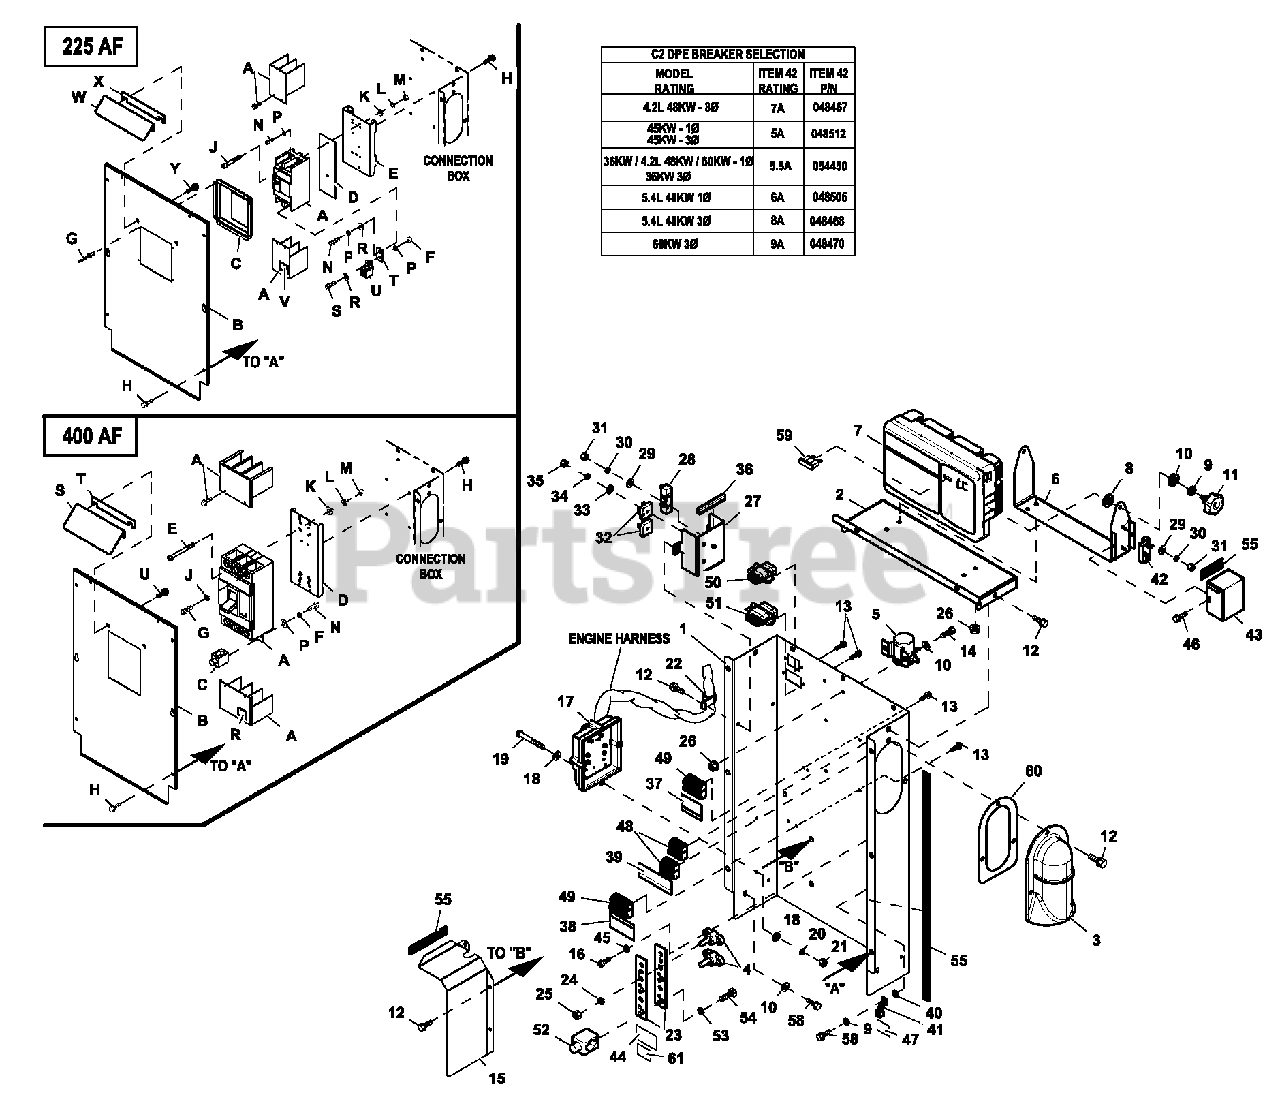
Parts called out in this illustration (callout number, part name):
1	BACK PANEL CONBOX SUPPORT C2
2	TOP PANEL CONBOX SUPPORT C2
3	COVER WIRE ENTRY CONBOX
4	JUNCTION BLOCK 3/8-16
5	RELAY SOLENOID 12VDC PNL MNT
6	BRACKET GIMBAL CONTROL PNL RAW
7	ASSY CTRL PROGRAMMED
8	WASHER FLAT NYLON 0.257 X 0.625
9	WASHER LOCK M6-1/4
10	WASHER FLAT 1/4-M6 ZINC
11	KNOB M6-1.0 CONTROL PANEL
12	SCREW HWHT M6-1 X 16 N WA Z/JS
13	SCREW HHSP #10 X 3/8 HI-LOW
14	SCREW HHC M6- 1.0 X 20 C8.8
15	SHIELD HIGH/LOW C2 RAW
16	SCREW PHTT M4-0.7 X 12 ZP
17	ASSY PROG 2010 IGN MOD 6 CYL
18	WASHER FLAT #10 ZINC
19	SCREW PPHM #10-32X2
20	WASHER LOCK #10
21	NUT HEX #10-32 STEEL
22	CLAMP STL/VNL 1.06 X .406 Z
23	NEUTRALoBLOCKo390/200 400Ao
24	WASHER LOCK 3/8
25	NUT HEX 3/8-16 STEEL
26	NUT FLANGE M6-1.0 NYLOK
27	COVER VOLTAGE SHIELD
28	RES WW 15R 5% 25W QK CONN
29	WASHER FLAT M3
30	WASHER LOCK M3
31	NUT HEX M3-0.5 G8 CLEAR ZINC
32	DIODE BRIDGE 1P 35A 1000V
33	WASHER FLAT M5
34	WASHER LOCK M5
35	NUT HEX M5-0.8 G8 CLEAR ZINC
36	TRIM VINYL BLACK 1/8GP (3"LG)
37	DECAL CUSTOMER POWER CONNECT
38	DECAL CUSTOMER CONTROL CONNECT
39	DECAL CONBOX TB1 CONNECTIONS
40	WASHER LOCK EXT 1/4 STL
41	LUG SLDLSS #2-#8 X 17/64 CU
42	CIRCUIT BREAKER
43	COVER DPE BREAKER NEXUS RAW
44	DECAL NEUTRAL
45	WASHER LOCK#8-M4
46	SCREW HHTT M4-0.7 X 8 ZP
47	DECAL GROUND LUG
48	TERM BLOCK 3P UL 12-20AWG
49	TERM BLOCK 4P UL 12-20AWG
50	MX150L SLRRMNT 22-18 8P W/O GA
51	MX150L SLRRMNT 22- 18 12P W/OGA
52	LUG SLDLSS 600/250-1/0X1/4-28
53	WASHER LOCK 1/4- M6 SS
54	SCREW HHC 1/4-28 X 3/4 G5
55	TAPE ELEC 1/2 FOAM (69"LG)
58	SCREW HHTT M6-1.0 X 16 ZYC
59	FUSE ATO TYPE 7.5AMP (BROWN)
60	GASKET WIRE ENTRY COVER
61	DECAL CAUTION ELEC SHOCK SM
A	CB 175A 2 POLE 240V 225AF
B	COVER CB C2 CPL
C	COVER CB DISH 2P G 225AF
D	INSULATOR CB 2P 225AF
E	STANDOFF CB BOX CONBOX
F	NUT HEX M8-1.25 G8 CLEAR ZINC
G	RIVET POP .125 X .275 SS
H	SCREW HWHT M6-1 X 16 N WA Z/JS
J	SCREW RHM #8-32X3-1/4
K	WASHER FLAT #8 ZINC
L	WASHER LOCK#8-M4
M	NUT HEX #8-32 STEEL
N	SCREW SHC M8-1.25 X 20 G8
P	WASHER LOCK M8-5/16
R	WASHER FLAT 5/16-M8 ZINC
S	SCREW SHC M8-1.25 X 25 C12.9
T	BUS BAR 200A LUG ADAPTOR
U	LUG SLDLSS 300 MCM-6 AL/CU
V	DECAL TERMINAL SHOCK HZD BI
W	SHIELD-SM CIRCUIT BREAKER
X	GASKET-CB SHIELD C2
Y	SCREW HWHTF M6-1.0X16
A	CB 0250A 3P 480V G 400AF
B	COVER CB 400AF C2 CONBOX
C	LUG SLDLSS 600/250-1/0X1/4-28
D	STANDOFF CB MOUNT CONBOX
E	SCREW RHM 10-32X4
F	WASHER LOCK M6-1/4
G	SCREW SHC M10-1.5 X 25 C12.9
J	WASHER LOCKM10
K	WASHER FLAT #10 ZINC
L	WASHER LOCK #10
M	NUT HEX #10-32 STEEL
N	SCREW HHC 1/4-28 X 1/2 G5
P	WASHER FLAT 1/4-M6 ZINC
R	DECAL TERMINAL SHOCK HZD BI
S	SHIELD-LGE CIRCUIT BREAKER
T	GASKET-CB SHIELD C2
U	SCREW HWHTF M6-1.0X16
